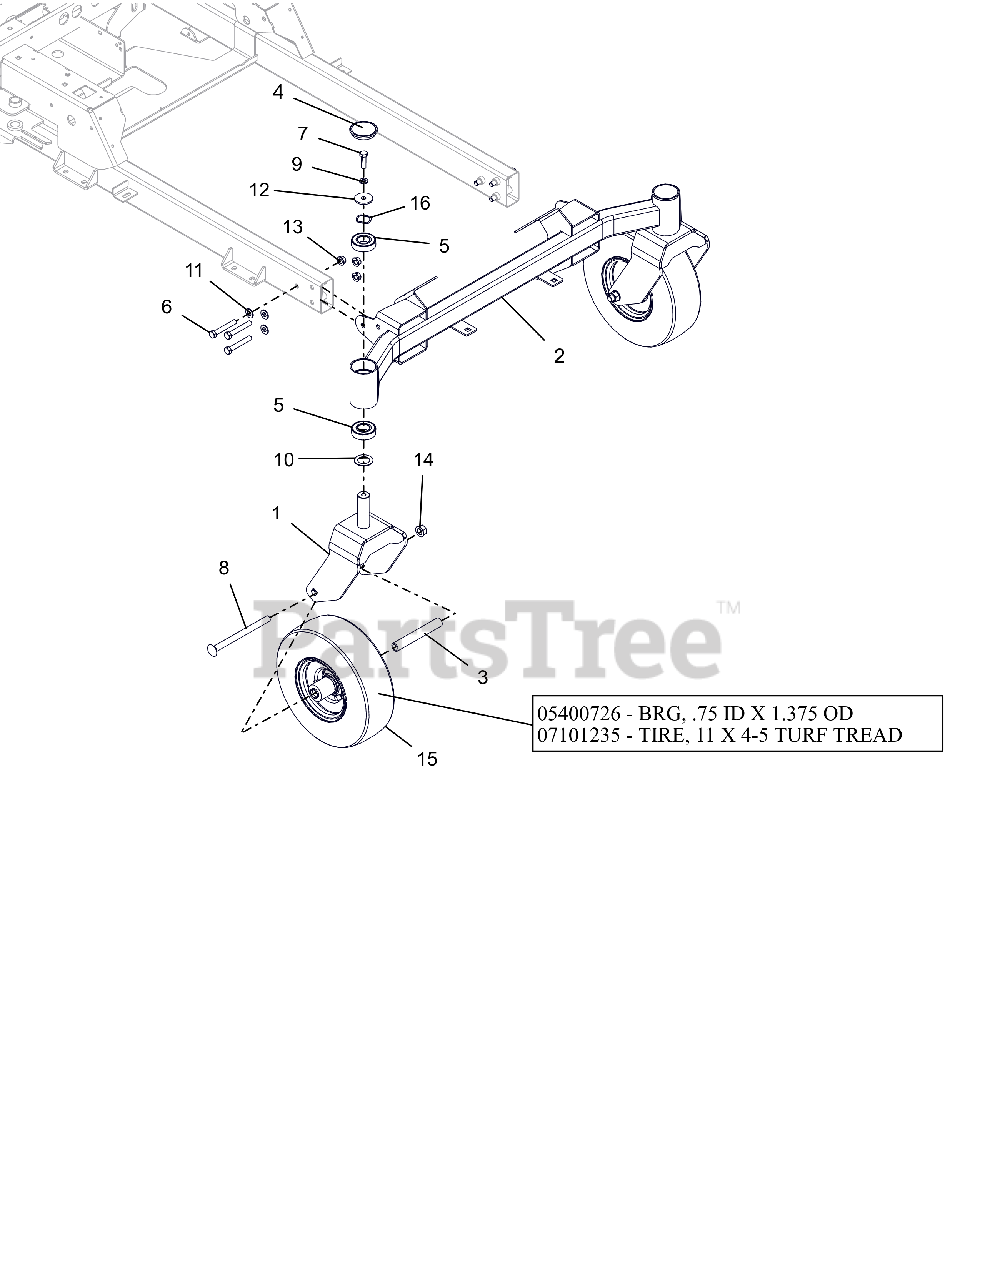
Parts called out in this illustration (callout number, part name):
1	WMT, CASTER FORK
2	WLDMT, AXLE FRONT
3	SPACER, ROLLED WHEEL
4	CAP, DUST
5	BRG,BALL 1.00X2.00X.563(1641)
6	BLT-HEX .38-16X2.50 GR8 YWZC
7	@BLT-HEX .38-16X1.25 GR5 YWZC
8	BLT-RDHDSQNK .50-13X6.50 GR5 Y
9	@WSHR-LK .38X.094 REG YWZC
10	WSHR-HRD-THRS 1.007X1.542X.062
11	WSHR-HDND .406X.812X.055
12	WSHR-FL-STL .380X1.50X.125YWZC
13	NUT-LK-TOP-FLG .38-16 GRG YWZC
14	@NUT-LK-TOP-FLG .50-13 YWZC
15	ASM, WHL/TIRE 11X4.00-5
15	BRG, .75 ID X 1.375 OD
15	TIRE, 11X4-5 TURF TREAD
15	TUBE 11 X4.0-5
16	WSHR-WAVE 1.0X1.25X.028 .145FH
